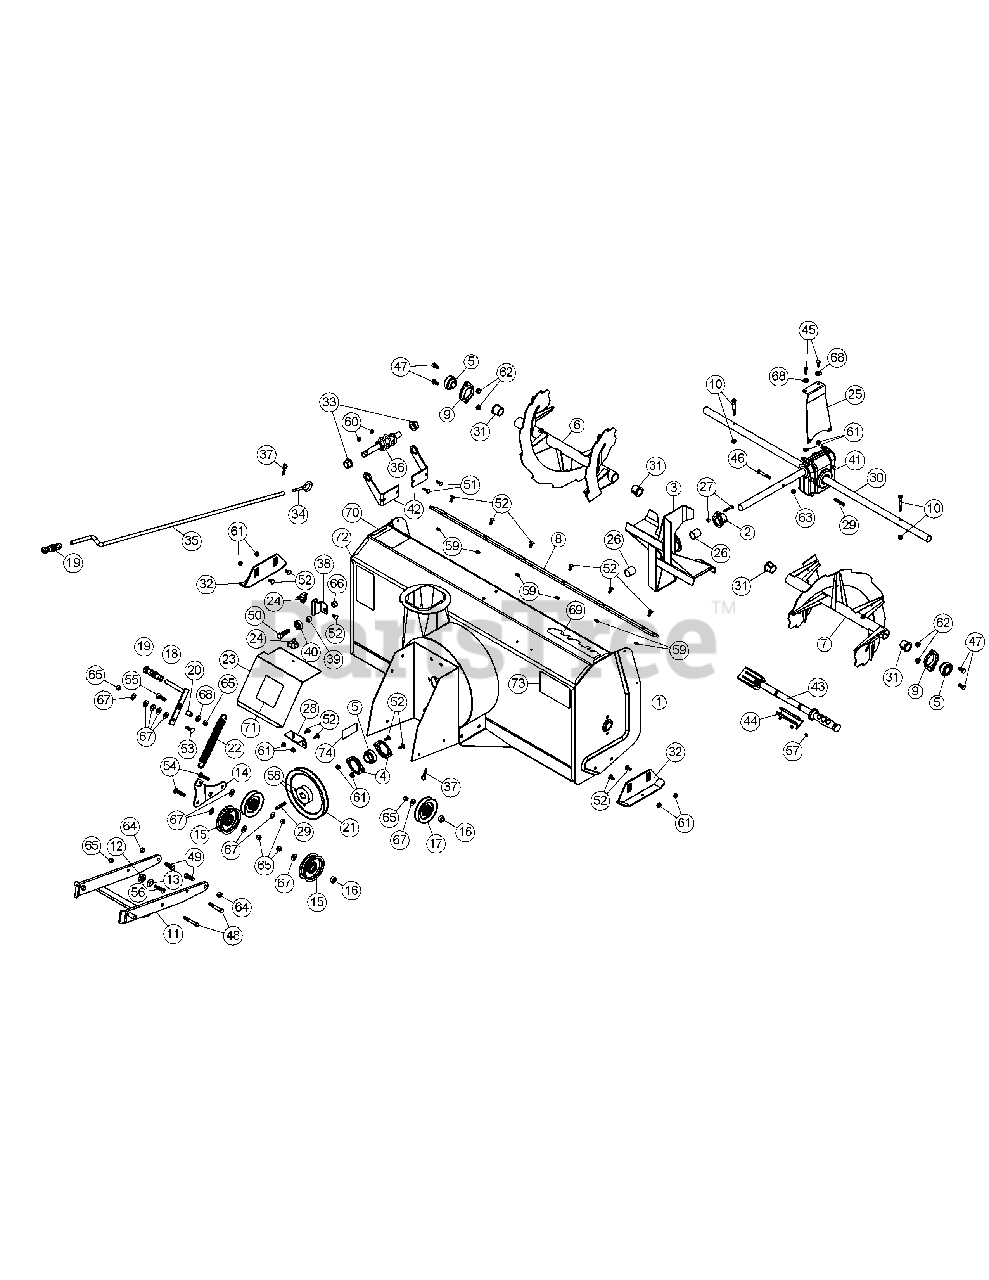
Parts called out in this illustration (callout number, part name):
1	Frame 48"
2	Shear plate
3	Fan
5	Bearing with set screw
6	Auger 48" left
7	Auger 48" right
8	Cutting edge 48"
10	Shear bolt / N.I.L.N. (auger)
11	Male hitch
12	Flange washer
13	Special washer
14	Tension lever
15	Flat pulley
18	Tension arm
25	Gear box support
26	Oil lite bushing
27	Shear bolt / N.I.L.N. (fan)
28	Belt guard support
29	Key 1/4" x 1/4" x 2"
31	Rotation bushing
33	Rotation bushing
34	Handle hook
36	Rotation worm
37	Hair pin 2.5mm
41	Gear box left rotation
42	Worm supports
43	Chute shovel
44	Chute shovel support
45	Hex. bolt 5/16" n.c. x 3/4" GR5
46	Hex. bolt 5/16" n.c. x 2 1/4" GR8
47	Hex. bolt 3/8" n.c. x 3/4" GR5
48	Hex. bolt 3/8" n.c. x 2 1/2" GR5
49	Hex. bolt 7/16" n.c. x 1 1/4" GR5
50	Hex. bolt 1/2" n.c. x 1 3/4" GR5
51	Carriage bolt 1/4" n.c. x 1 " GR5
52	Carriage bolt 5/16" n.c. x 3/4 " GR5
53	Carriage bolt 3/8" n.c. x 1 1/4 " GR5
54	Carriage bolt 3/8" n.c. x 1 3/4 " GR5
55	Carriage bolt 3/8" n.c. x 1 1/2 " GR5
56	Hex socket f.h. cap screw 3/8" n.c. x 1-3/4"
57	Socket Head Cap Screw M5 x 0.80 x 10
58	Socket head set screw 5/16"' n.c. x 5/16''
59	Stover lock nut 5/16" n.c.
60	Flange nut 1/4" n.c.
61	Flange nut 5/16" n.c.
62	Flange nut 3/8" n.c.
63	Nylon Insert lock Nut 5/16" n.c. GR5
64	Nylon Insert lock Nut 7/16" n.c.
65	Nylon Insert lock Nut 3/8" n.c.
66	Nylon Insert lock Nut 1/2" n.c.
67	Flat washer 7/16" hole
68	Flat washer 3/8" hole
69	Decal Cub Cadet
70	Decal danger auger
71	Decal danger belts
72	Decal read instructions
73	Decal warning safety
